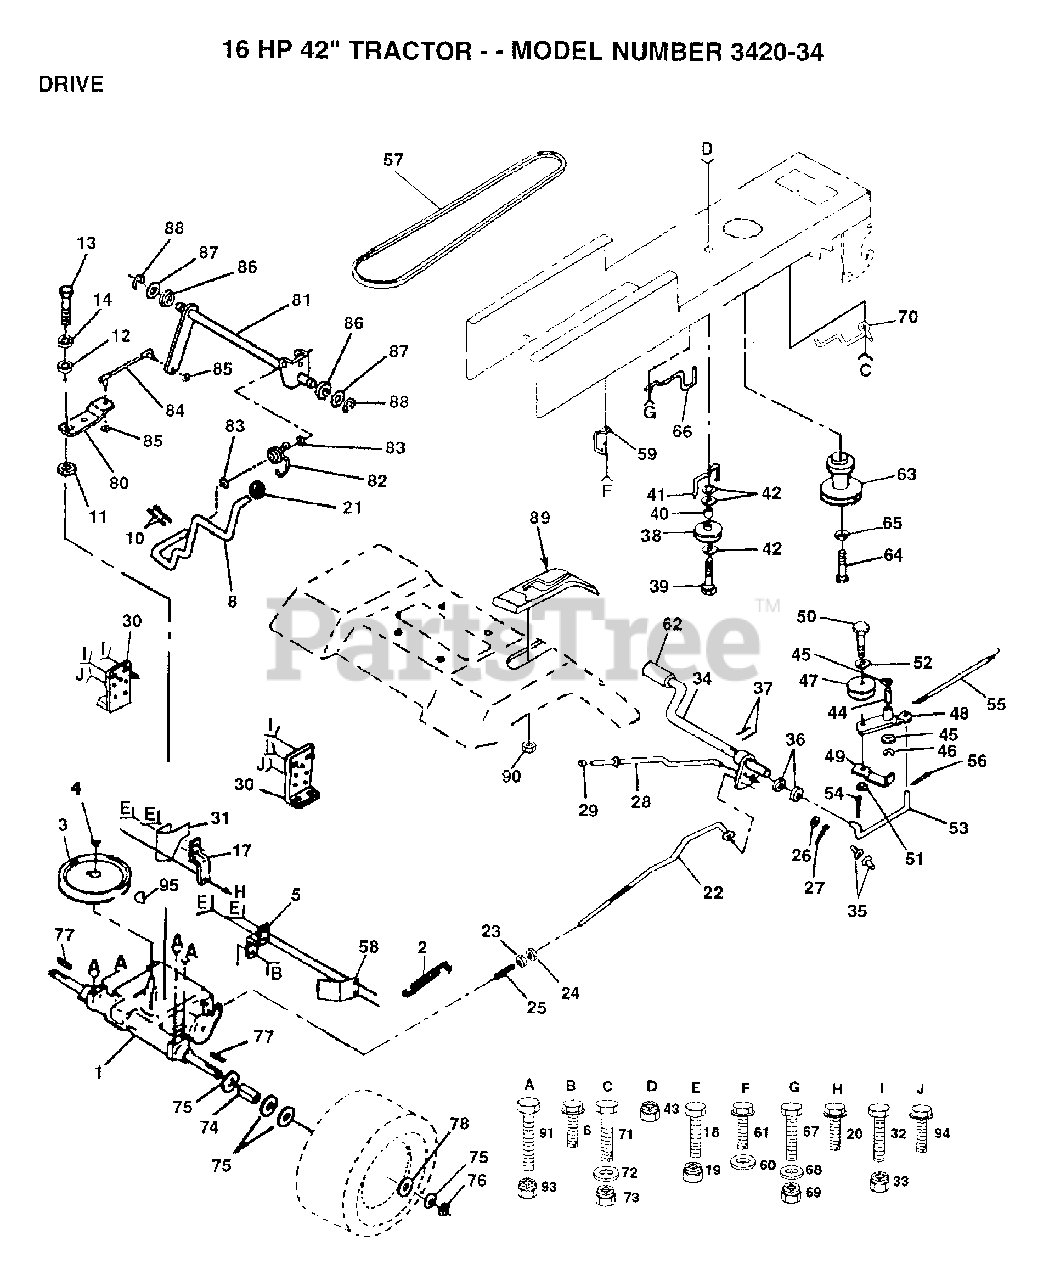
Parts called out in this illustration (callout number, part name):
3	"PULLEY,TRANSAXLE"
5	STRAP TORQUE
6	SCREW
10	PIN COTTER 1/8
11	WASH-SHFT PLT LT
12	WASHER
14	LOCKWASHER
17	STRAP TORQUE
20	SCREW
21	KNOB T (1/2-HOLE)
22	BRAKE ROD
23	NUT
24	NUT
25	SPRING ROD LT
26	WASHER
27	COTTER PIN
28	BRAKE PARK ROD
29	PLUNGER CAP T
30	TRANSAXLE MTG BKT
31	"KEEPER,BELT LH"
32	BOLT
35	NYLON BEARING
36	WASHER LT
38	PULLEY.IDLER.FLAT
39	BOLT
40	SPACER T
41	BELT KEEPER LT
42	WASHER
44	"LY, BEARING"
45	WASHER LT
46	KLIP RING
48	ARM IDLER
49	RETAIN BELT
52	WASHER HYT
53	"LINK, CLUTCH T"
54	COTTER PIN
55	"SPRING, RETURN LT"
56	COTTER PIN
57	BELT-V
58	"KEEPER,BELT RH"
60	WASHER
61	SCREW
62	PEDAL COVER T
64	BOLT
65	LOCKWASHER
66	KEEPER.BELT.ENG.L
67	BOLT
68	WASHER
70	KEEPER BELT ENG
71	BOLT
72	WASHER
74	SPACER LT
75	WASHER
76	E-RING LT
77	SQUARE KEY
78	WASHER
80	ARM SHIFT TRANS
81	SHAFT ASM.SHIFT
82	"SPRING,TORSION"
83	WASHER
84	TIE ROD
85	NUT 1/4-28
86	BUSHING
87	WASHER D
88	KLIP RING
90	NUT
91	BOLT
94	SCREW
